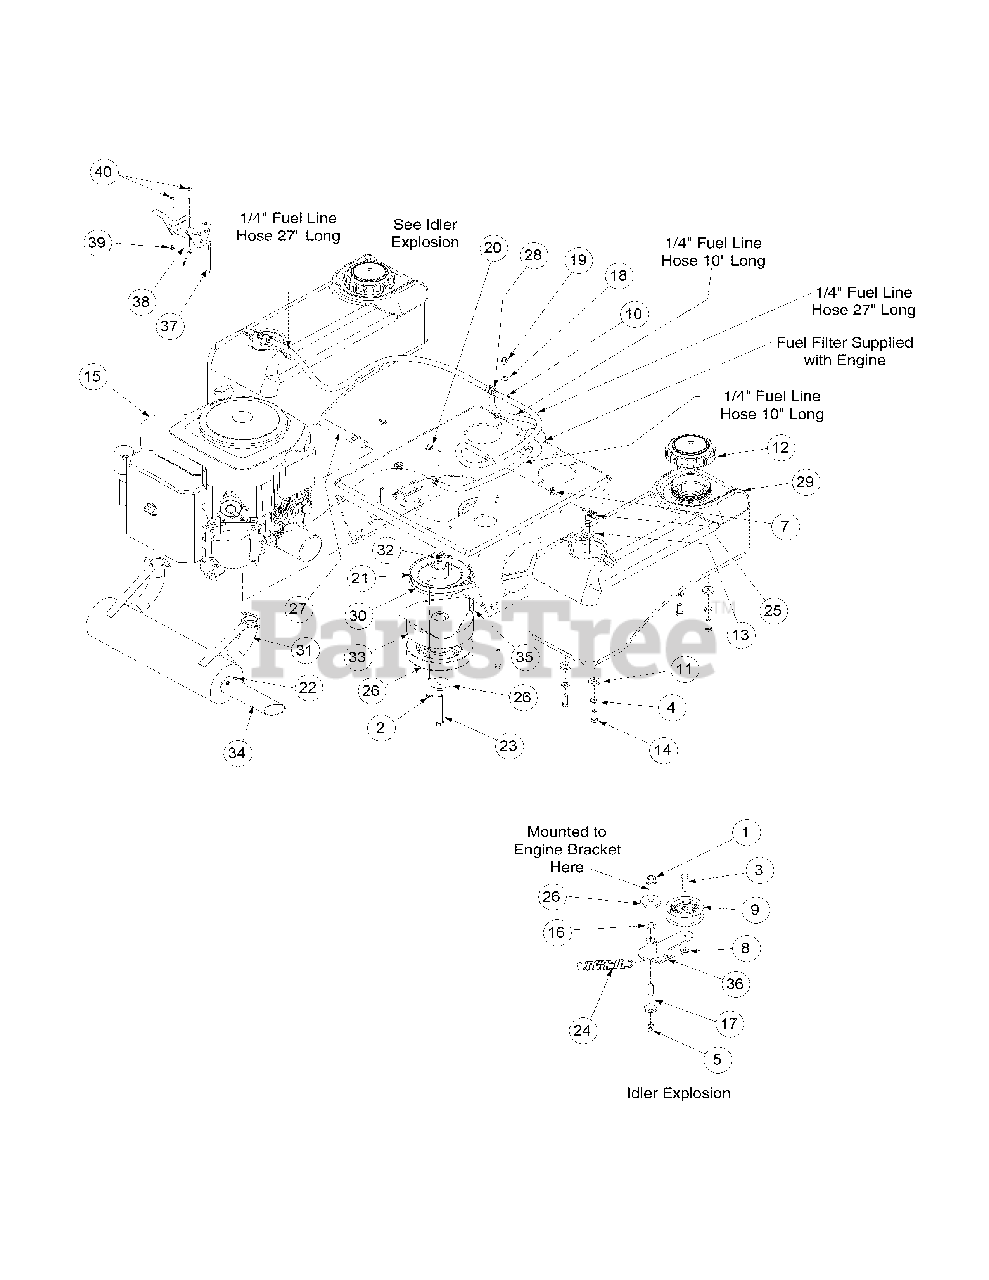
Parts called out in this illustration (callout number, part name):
1	Nut, 7/16-20, Flange Lock
2	HHCS, 5/16-18, 1-3/4
3	Hex Head Cap Screw, 3/8-16 x 1.50
4	Lock Washer, 3/8
5	Grease Fitting, 90 degree
6	Hose, 1/4" Fuel Line, 74 inches
7	Clamp, Union
8	Nut, Hex 3/8-16 Flange Lock
9	Idler Pulley w/ Adaptor
10	Clamp, 1/2 Tubing
11	Idler Washer
12	Fuel Cap, 3.5
13	Grommet, Fuel Tank
14	Hex, Cap Screw, 3/8-16, .88
15	23HP Kohler Engine
16	Flat Washer, .469 ID, .875 OD, .105
17	Shoulder Bolt
18	Flat Washer, 1.4 x .630 x .0515
19	Screw, TT, 1/4-20, 0.75, Hex Index Washer
20	Nut, Lock, HexFlange, 5/16-18
21	Trans Drive Pulley
22	Screw, 8-32 x 0.375
23	Hex Head Cap Screw, 7/16-20 x 3.00
24	Extension Spring, .865 OD x 4.18 lg Version 2
24	Extension Spring, .865 OD x 4.68 lg Version 1
25	Fuel Pickup Fitting
26	Flat Washer, 7/16 ID x 1.75 OD x .25
27	Oil Drain Hose
28	Tee Fitting, Fuel
29	Fuel Tank
30	V Belt, A Section x 47.3
31	23HP Kohler Exhaust
32	Key, 1/4 x 1/4 x 2.75
33	Clutch Electric, Ogura JD08
34	Straight Exhaust Pipe
35	Clutch Retainer Assembly
36	Idler Arm Assembly
37	Choke Control Cable
38	Throttle Control Cable
39	Nut, #10-24
40	Screw,TT,Hex Index Washer #10-20,.75
